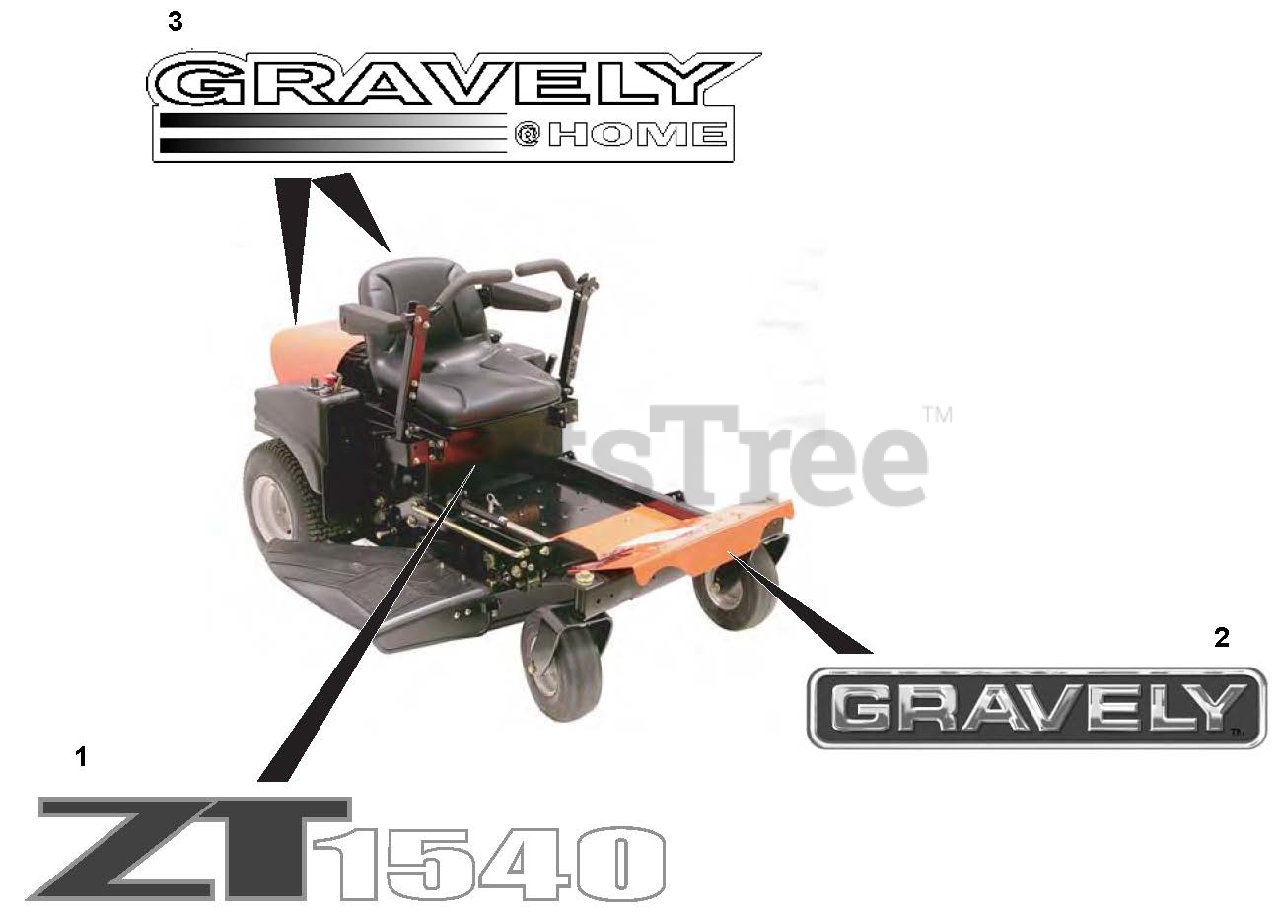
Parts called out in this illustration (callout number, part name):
1	Decal, Mini ZT 1434
2	Decal, Mini ZT 1540
2	Decal, Gravely Jewel
3	Decal, Gravely @ Home
